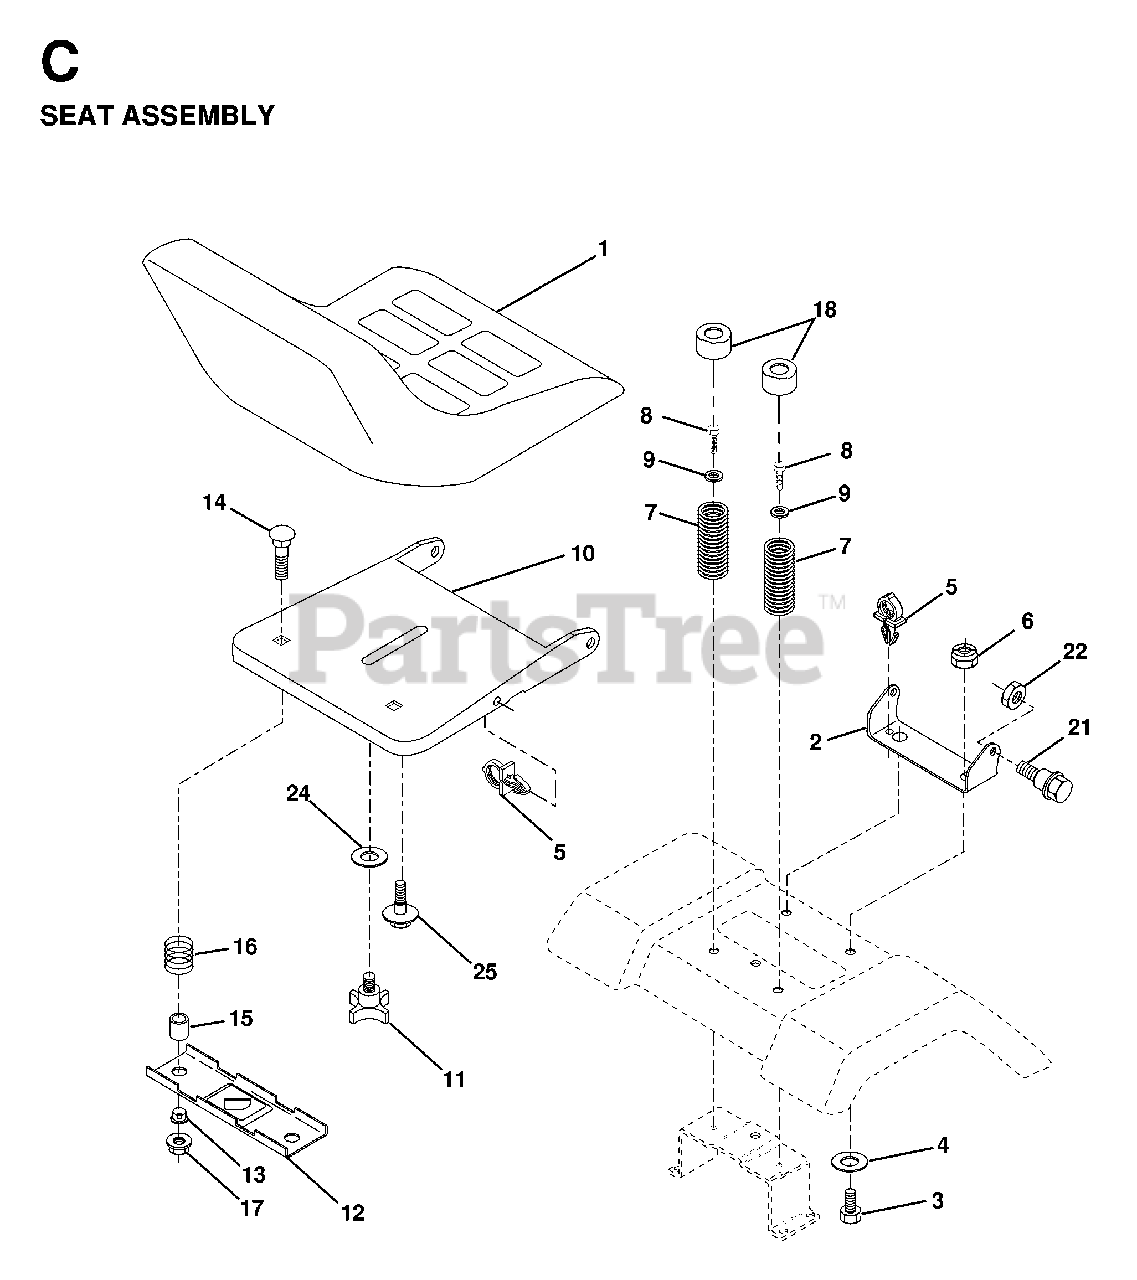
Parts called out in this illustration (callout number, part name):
1	SEAT
2	SEAT PIVOT BRKT
3	BOLT
4	WASHER PM
5	PUSH CLIP
6	NUT
7	SPRING COMPRESSION
8	SCREW GTV
9	WASHER
10	PAN, SEAT
11	KNOB 1/2" YT
12	BRKT SWITCH
14	BOLT.ROUND.HEAD.SQUARE.NECK
15	SPACER SPLIT
16	SPRING COMPRESSED
17	NUT T
18	CAP SPRING
21	BOLT SHOULDER 5/16-18
22	LOCKNUT
25	BOLT,SHOULD
